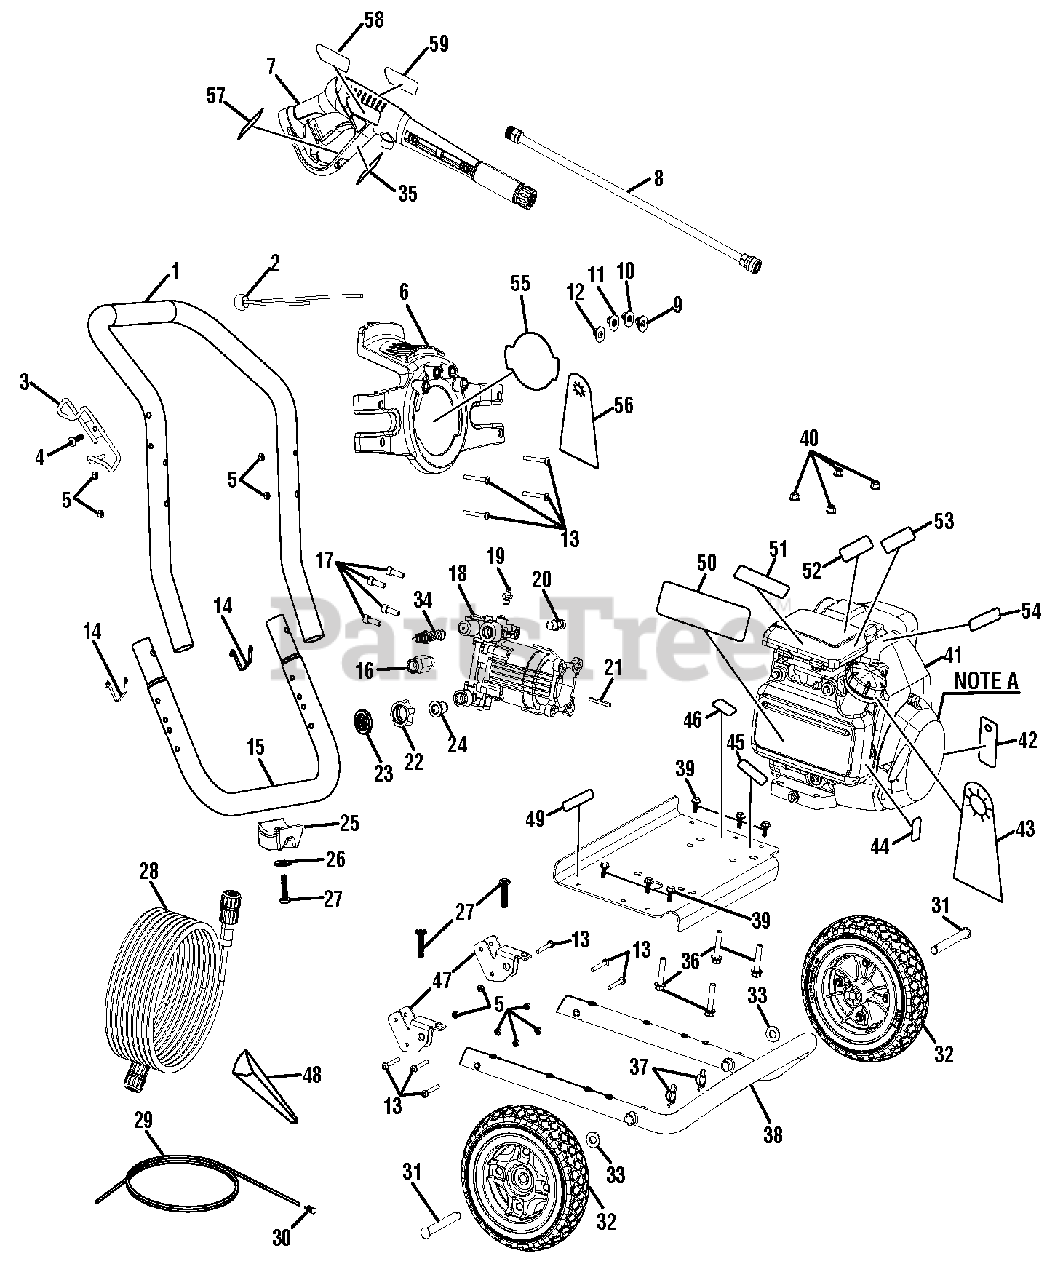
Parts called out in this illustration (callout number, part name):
1	Handle w/Foam
2	Bungee Cord and Bead Assembly
3	Wand Holder
4	Screw (M6 x16 mm, Phillips Pan Hd)
6	Hose and Nozzle Holder
7	Trigger Handle Assembly
8	Extension Wand
9	0deg Nozzle
10	25deg Nozzle
11	40deg Nozzle
12	Soap Nozzle
13	Screw, (M6 x 48 mm T30 Torx Hd)
14	Lock Button w/Spring Clip
15	Rear Frame Assembly
16	Outlet Tube
17	Screw (5/16-24 x 23 mm, Hex Soc. Cap Hd.)
19	Detergent Suction Kit
20	Thermal Release Valve
21	Output Shaft Key (40 mm)
23	Filter Screen (Pump Inlet)
25	Rubber Foot
27	Bolt (M6 x 25 mm, Flange Hd.)
28	Hose (25 ft., 3000 psi)
29	Detergent Injection Tube
30	Detergent Injection Filter
33	Washer (1/2 in.)
34	Pump Unloader Valve
35	Label (Trigger Guard Warning)
36	Bolt (M8 x 40 mm, Hex Hd.)
37	Ring Clip
38	Main Frame Assembly
39	Bolt (M6 x 16 mm, Flange Hd.)
40	Nut (M8 x 1.25 mm, Flange)
42	Label (Oil Hang Tag)
43	Label (Notice Hang Tag)
44	Label (Do Not Mix)
45	Label (Combustion Eng/Sp)
46	Label (Add Oil)
47	Frame Connector
49	Label (Pump Quick Start)
50	Label (Danger - Bilingual)
51	Label (Inquires)
52	Label (E85)
53	Label (Engine Quick Start)
54	Label (Hot Surface)
55	Label (Performance)
56	Nozzle Hang Tag
57	Label (Wand Rating)
58	Label (Wand Logo)
59	Label (Wand Warning)
